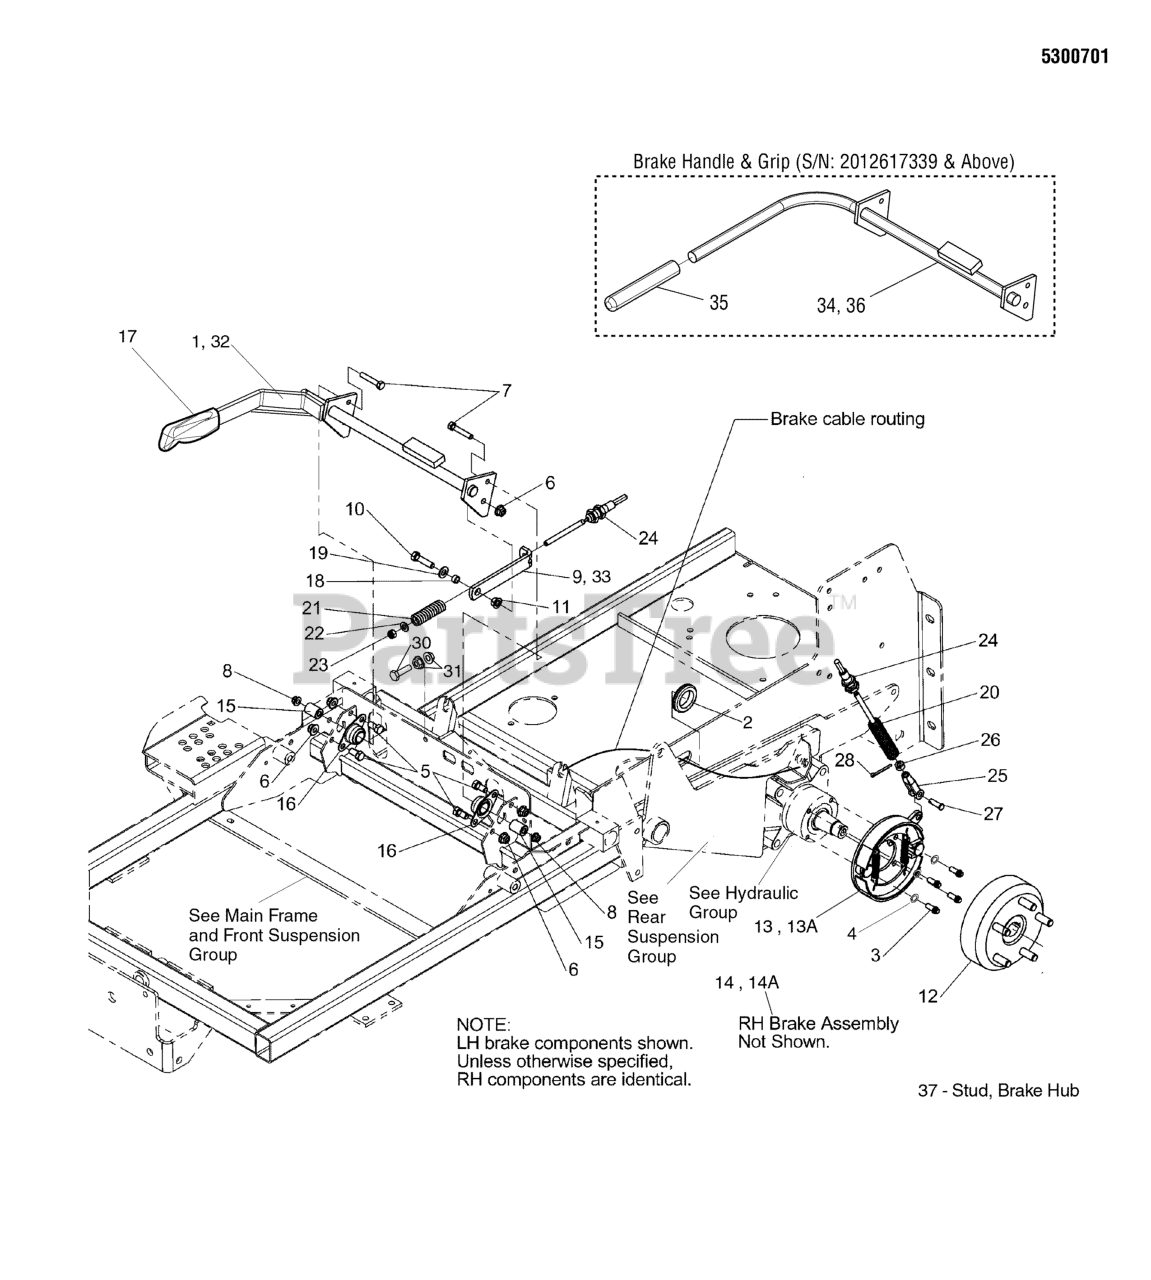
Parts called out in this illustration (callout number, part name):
1	WELD, BRAKE SHAFT - RED MODEL
2	GROMMET, 1-1/4
3	BOLT, 5/16-18 X 3/4 12PT FLANGE - PATCH
4	WASHER, 5/16 LOCK CZ
5	BOLT, 3/8-16 X 3/4" GD5 CZ
6	NUT, 3/8-16 HEX NYLOCK FLANGE
7	BOLT, 5/16-18 X 1-3/4" GD5 YZ
8	NUT, 5/16-18 HEX NYLOCK FLANGE
9	LINK, BRAKE LOCK - BLK
10	BOLT, 3/8-16 X 1-1/2" GD5 CZ
11	NUT, 3/8-16 HEX SERRATED FLANGE
12	BRAKE DRUM, 6", 5 BOLT, KNOTT
13	BRAKE SHOE ASM, LH, KNOTT
13A	BRAKE ASSEMBLY, LH
15	SPACER, .32 X .75 X 1.06
16	BEARING, BRONZE FLANGE, 3/4
17	GRIP, BLACK FLEXIBLE
18	SPACER, .38 X .50 X .27
19	WASHER, 3/8 SAE
20	SPRING, COMPRESSION
21	SPRING-COMP, .75 X .162 X 2.5
22	WASHER, 5/16" SAE
23	NUT, 5/16-24 HEX NYLON LOCK
24	CABLE, PARKING BRAKE
25	CLEVIS, 5/16-24, PLASTIC
26	NUT, 5/16-24 HEX
27	PIN, CLEVIS, 5/16" X 1
28	PIN, HAIR, .0585" X 1-1/8"
30	BOLT, 5/16-18 X 1-1/4" GD5 YZ
31	NUT, 5/16-18 HEX SERRATED FLANGE (LARGE)
32	WELD, BRAKE SHAFT - ORANGE MODEL
33	LINK, BRAKE LOCK - BLK
34	WELD, BRAKE SHAFT - RED MODEL
35	GRIP, FOAM, 3/4 ID X 6 X .187
36	WELD, BRAKE SHAFT - ORANGE MODEL
37	STUD, BRAKE HUB (SV)
